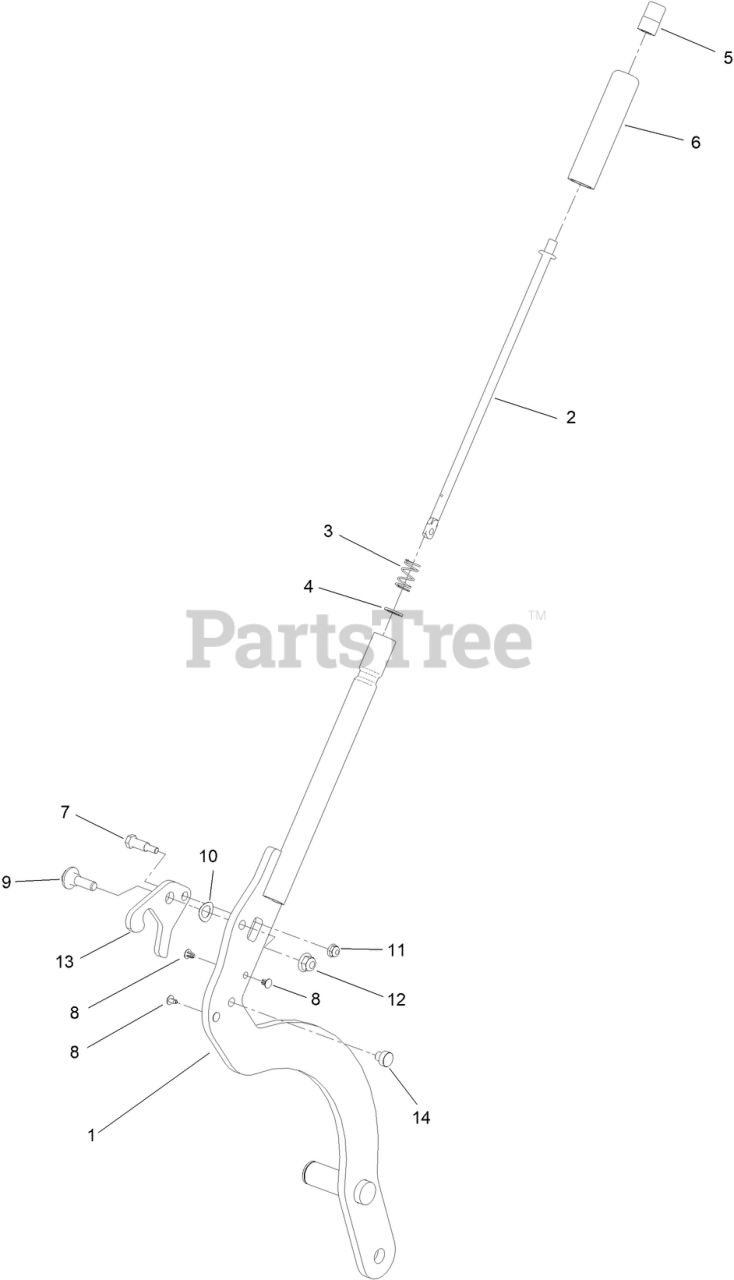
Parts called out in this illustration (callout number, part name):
1	LEVER-LIFT
2	ROD-LATCH, RELEASE
3	SPRING-COMPRESSION
4	WASHER-SPECIAL
7	BOLT-SHOULDER
9	SCREW-SHOULDER, HWH
10	WASHER-SPRING
11	NUT-HF
12	NUT-HF, NI
13	LATCH-HOC
14	PLUG-WEAR
